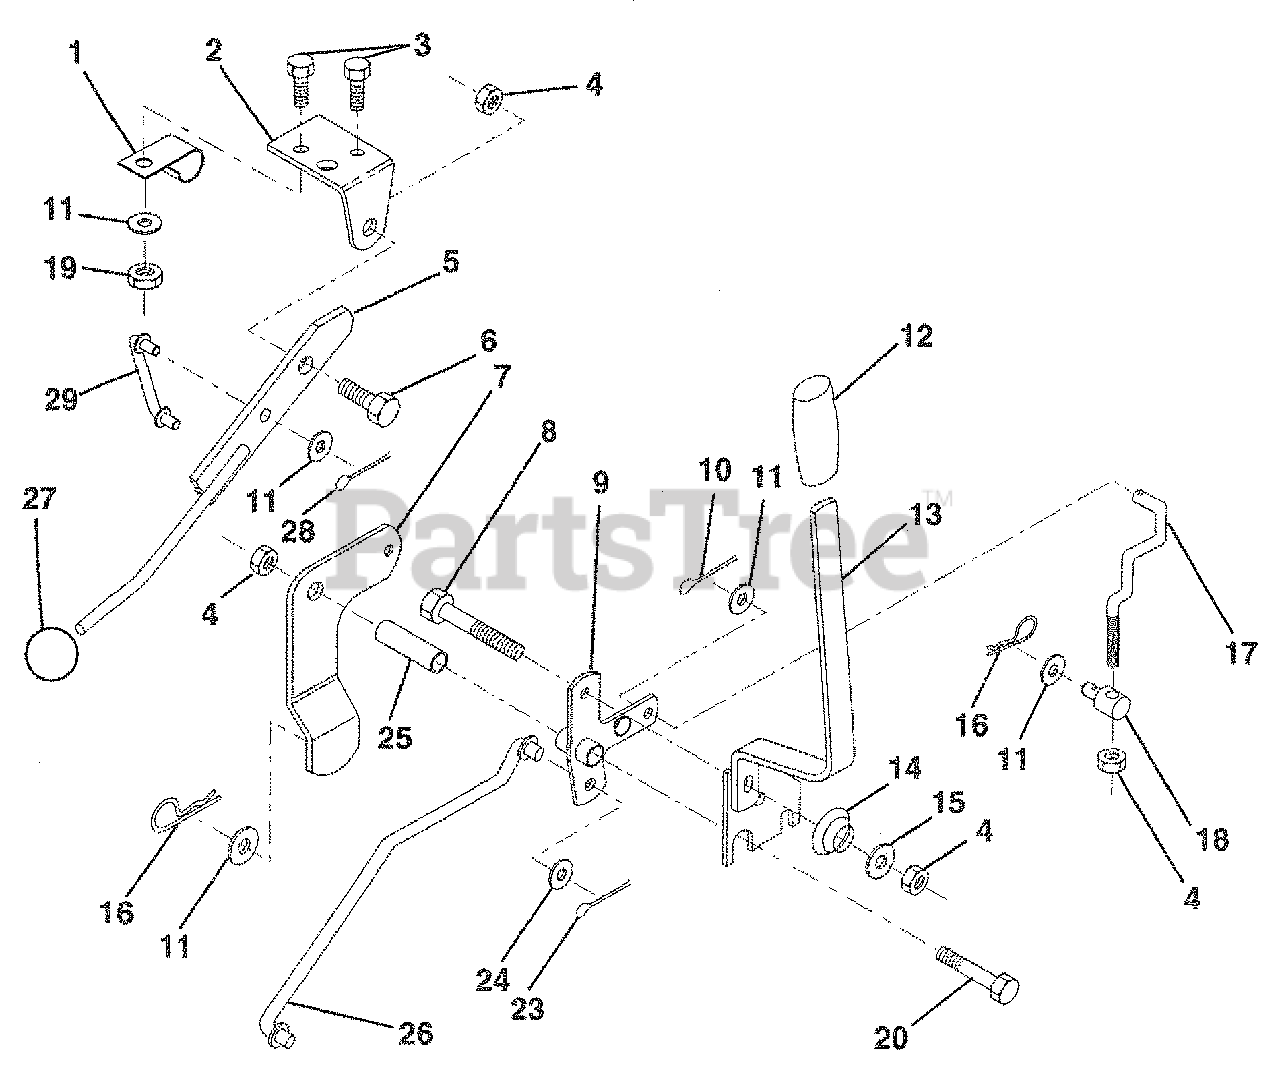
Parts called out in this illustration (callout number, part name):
1	Clip, Insulated
2	Bracket, Mower Clutch
3	Bolt, Fin. Hex 1/4-20 UNC x 1/2 Gr. 5
4	Nut, Crownlock 3/8-16 UNC
5	Assembly, Clutch Lever
6	Bolt, Shoulder
7	Assembly, Mower Clutch Arm
8	Bolt, Hex 3/8-16 UNC x 2-1/4
9	Assembly Bracketiff
10	Pin, Cotter 1/8 x 3/4
11	Washer 13/32 x 13/16 x 16 Ga.
12	Grip, Handle
13	Assembly, Lift Handle
14	Spring, Compression
15	Washer 13/32 x 3/4 x 12 Ga.
16	Retainer, Spring
17	Link, Front Lift
18	Trunnion, Threaded 3/8-16
19	Nut, Crownbck 1/4-20
20	Bolt, Fin. Hex 3/8-16 UNC x 2 -3/4
23	Pin, Cotter 1/8 x 1
24	Washer 17/32 x 1 x16 Ga.
25	Tuba, Specer
26	Rod, Mower Lift
28	Pin, Cotter 3/32 x 3/4
29	Link, Mower Clutch
